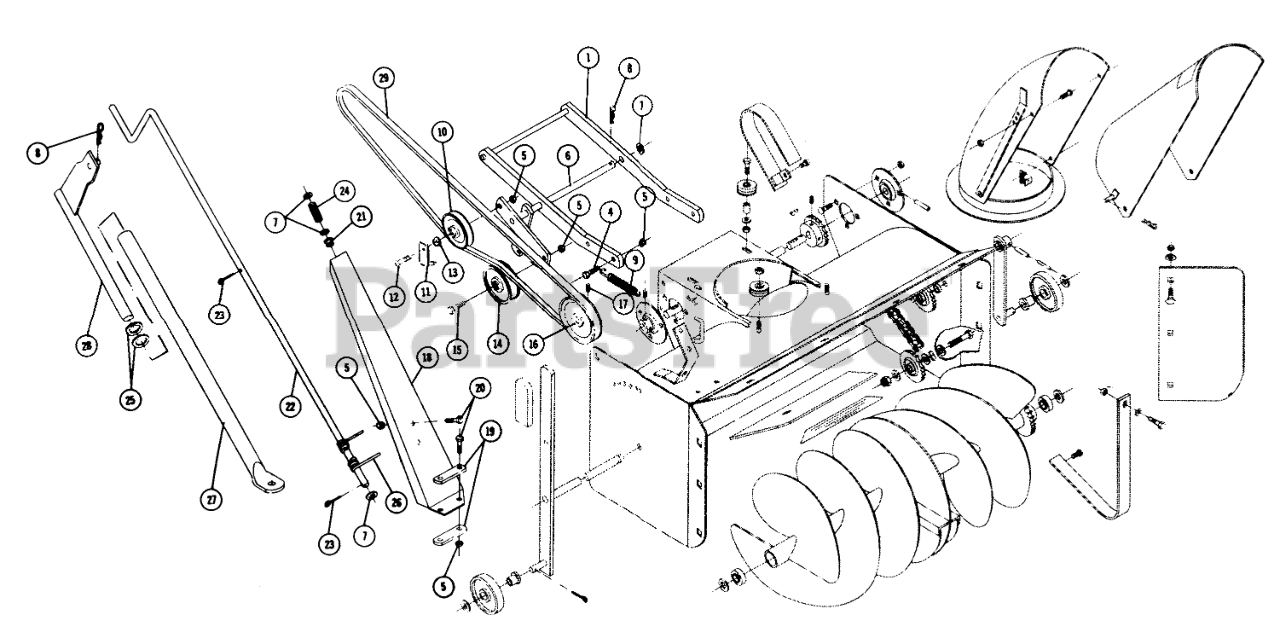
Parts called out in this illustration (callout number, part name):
1	Mounting Frame
4	Bolt 3/8-16 x 7/8
6	ASSY IDLER ARM R
7	Washer
8	Hairpin
9	SPRING R
10	PULLEY-IDLER
11	Spacer
12	Bolt Hex 3/8-16 x 1 3/4
13	Spacer
14	Idler Pulley
15	Bolt, 3/8-16 x 1/2
16	Pulley
17	Set Screw
18	Crank Support
19	Bar-Reinforcing
20	Bolt 3/8-16 x 3/4
21	NYLINER BUSHING
22	Crank
23	Cotter Pin
24	SPRING-COMPRESSION
25	Washer
26	Cable
27	Tube-Lift
28	Lid Rod
29	V-BELT
